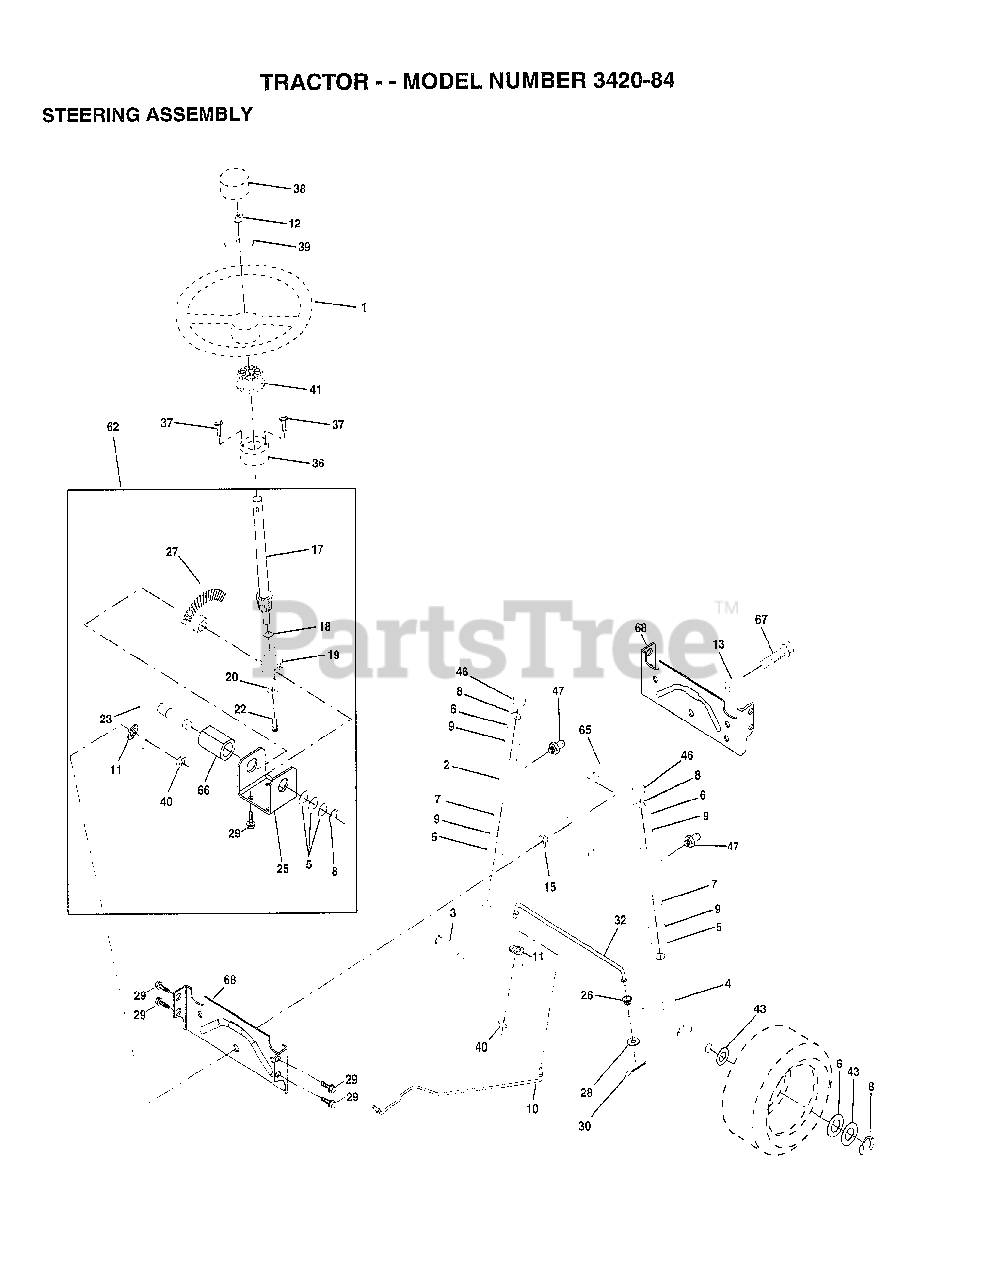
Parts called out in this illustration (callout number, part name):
2	AXLE ASM
3	SPINDLE.ASM.LH
4	"SPINDLE ASM,RH"
6	WASHER
7	WASHER
8	RING
9	COL. SRTG. BEAR.
10	DRAGLINK-STAMPED
11	LOCKWASHER
13	BEARING AXLE
15	"NUT-LOC,FLANGE LT"
17	SHAFT ASM STEERNG
18	THRUST WASHER
19	SUPPORT.SHAFT
22	SCREW HEX SOC1/4-
25	BRKT-STEERING
26	BUSHING.DRAGLINK
27	GEAR SECTOR
28	WASHER
29	SCREW
30	COTTER PIN
32	TIE ROD
36	BUSHING.STRG.3/4
37	"SCREW-TT,10-32 FL"
38	"INSERT,STR WHEEL"
39	WASHER
40	GRIPCO NUT
41	ADAPTER LT
43	WASHER
46	CAP
47	ZERK M
62	KIT STEERING ASM
65	SPACER AXLE
66	"BEARING-ARM,PITMA"
67	BOLT
68	BRACE AXLE
